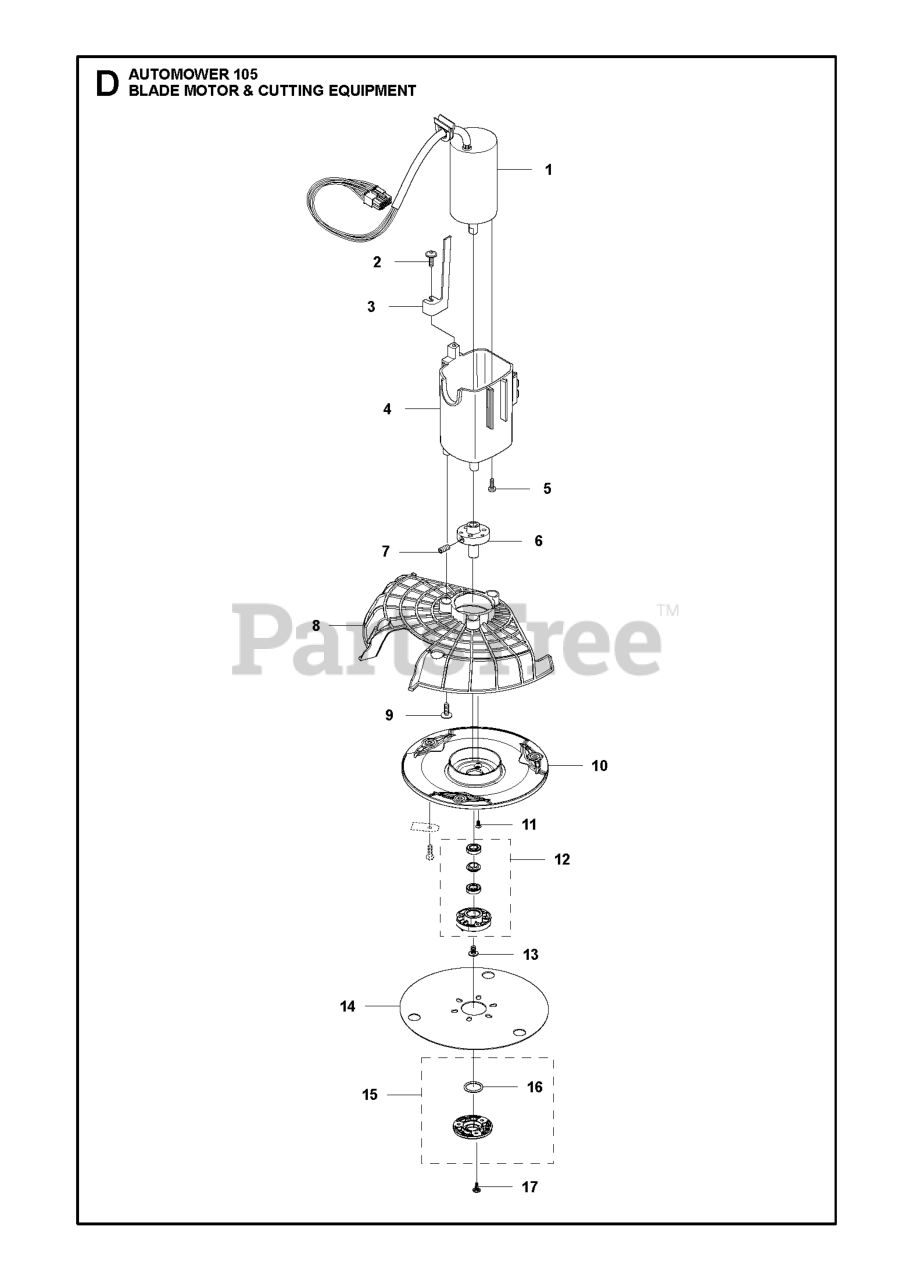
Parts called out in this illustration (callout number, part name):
1	MOTOR CUTTING, TYPE 2
2	SCREW 14MM
3	HEIGHT INDICATOR
4	MOTOR HOUSING
5	SCREW ITXPANM M4X12 8.8 ZP-BC
7	SCREW IHSETM M5X10 8.8 ZP-BC
9	SCREW 14MM
11	SCREW
12	BEARING HOUSING ASSY SPARE PAR
15	COVER KIT BEARING
16	O-RING 20X2,5 MM
17	SCREW 14MM
